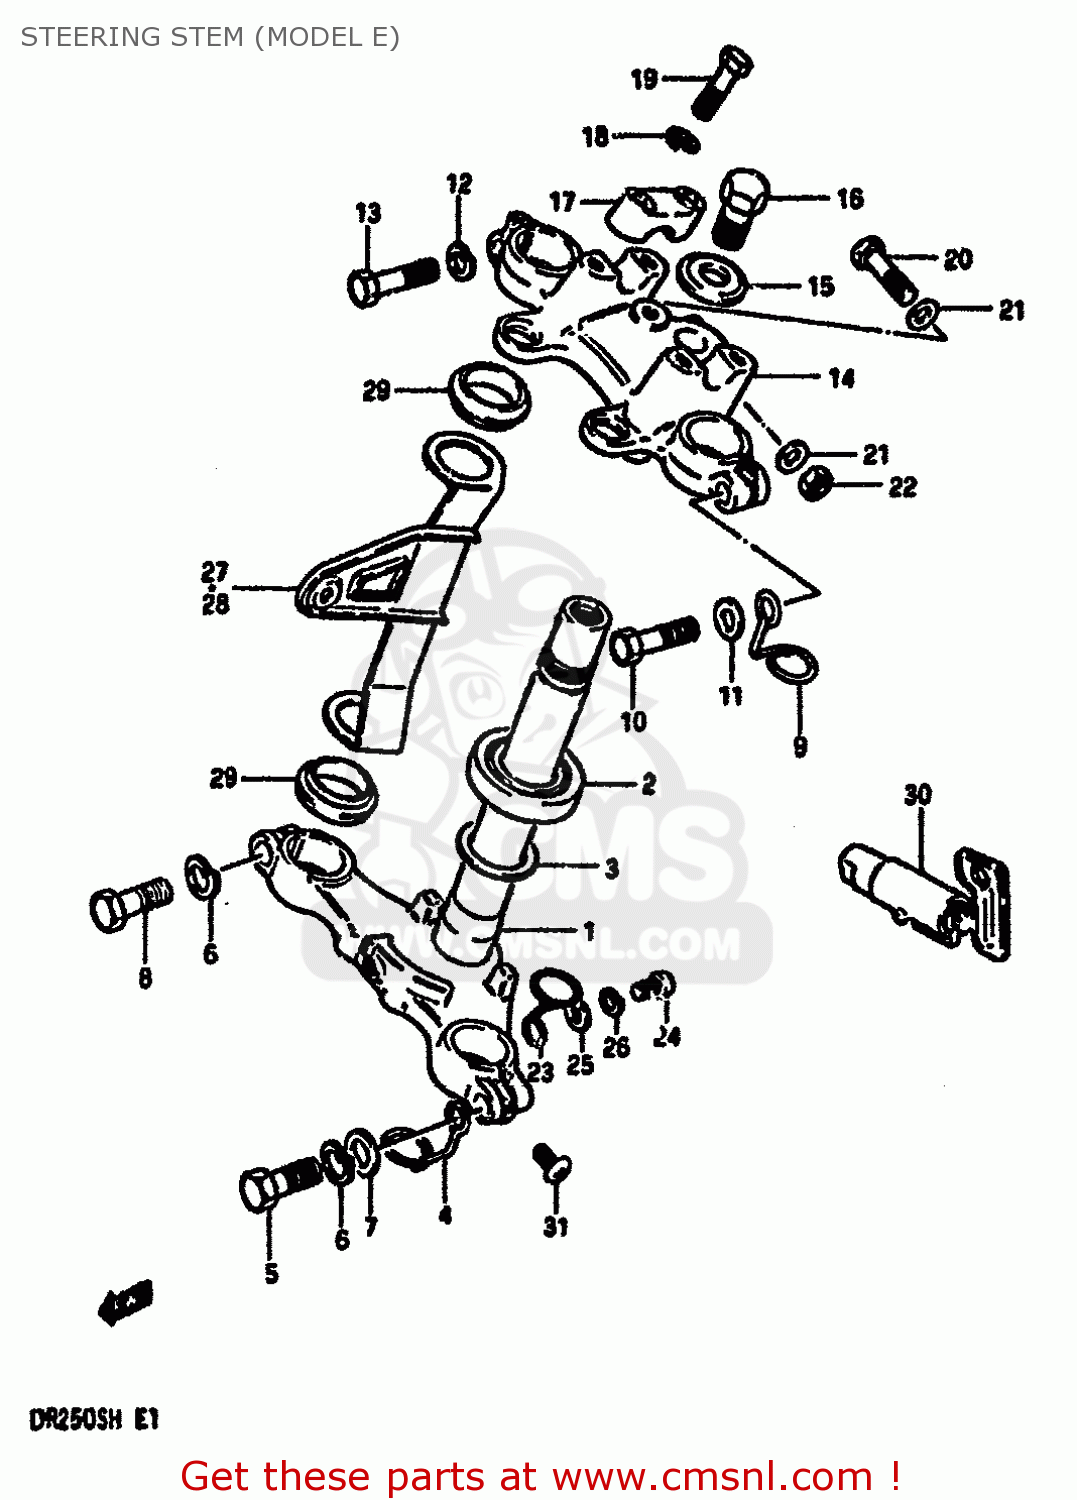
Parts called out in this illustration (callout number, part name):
1	STEM,STEERING
2	BEARING
3	WASHER,THRUST
4	CLIP
5	BOLT 12X45
6	WASHER,LOCK 12
7	WASHER
8	BOLT
9	CLIP
10	BOLT 10X40
11	WASHER
12	WASHER,LOCK,10
13	BOLT,FORK INNER TUBE F
14	HEAD,STEERING STEM
15	WASHER
16	BOLT,STEERING STEM HEAD
17	HOLDER,HANDLEBAR
18	LOCK WASHER
19	BOLT
20	BOLT 8X50
21	WASHER
22	NUT
23	CLIP
24	SCREW
25	WASHER
26	WASHER,LOCK
27	BRACKET,HEADLAMP,RIGHT
28	BRACKET,HEADLAMP,LEFT
29	GASKET
30	LOCK ASSY,STEERING(NEIMAN)
31	SCREW 5X6
